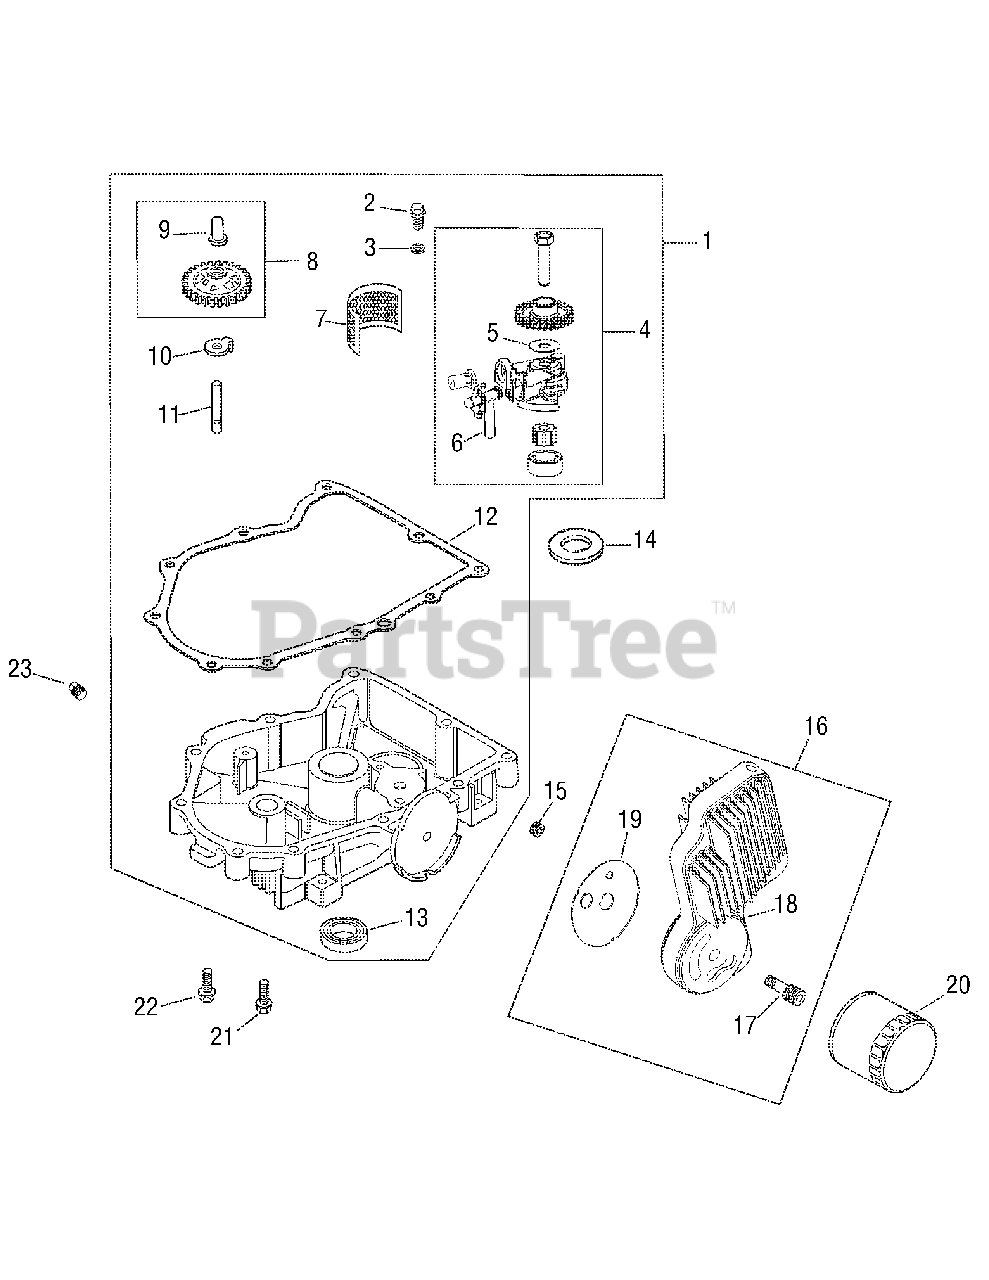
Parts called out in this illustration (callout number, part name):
1	Kit, oil pan w/gasket (Includes 2-13)
2	Screw, hex. flange M6 x 1.0 x 25
3	Washer, plain 6 mm
4	Oil pump assembly (Includes 5,6)
5	O-Ring, oil pick-up
6	Tube, oil pickup
8	Kit, governor gear (Includes 9)
9	Pin, governor regulating
11	Shaft, governor gear
12	Gasket, oil pan
13	Seal, oil (PTO end)
15	Plug, hex. ctsk. 3/8"
16	Kit, oil cooler (Includes 17-19)
17	Nipple, oil filter
19	Gasket, oil filter adapter
20	Filter, oil
21	Screw, hex. flange M8 x 1.25 x 45
22	Screw, hex. flange M8 x 1.25 x 45
23	Plug, pipe 3/8" square hd.
